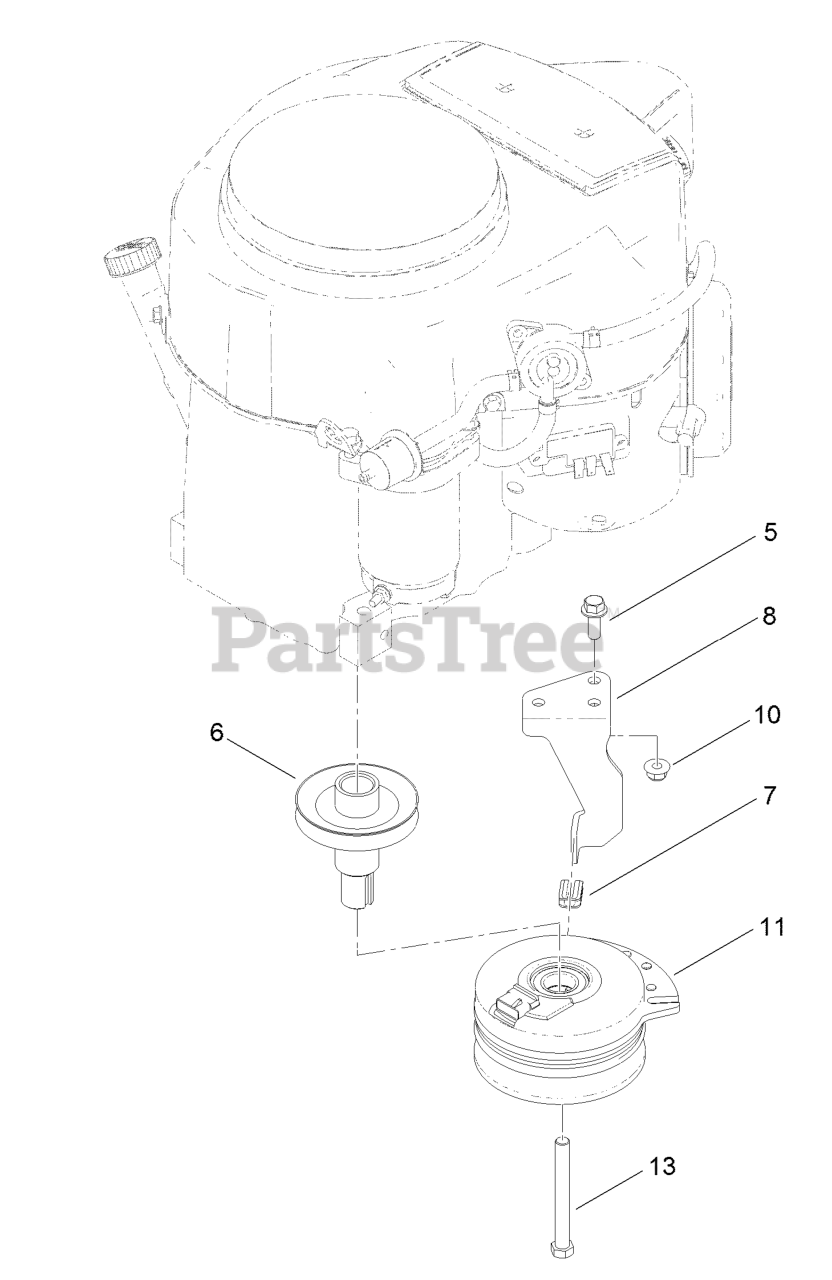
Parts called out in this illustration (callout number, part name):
5	SCREW-HHF 3/8-16 X 1
6	PULLEY-ENGINE
7	ISOLATOR-CLUTCH
8	STOP-CLUTCH (NARROW)
10	NUT-HF, NI
11	CLUTCH-ELECTRIC
13	PIN-ROLL, SLOTTED
